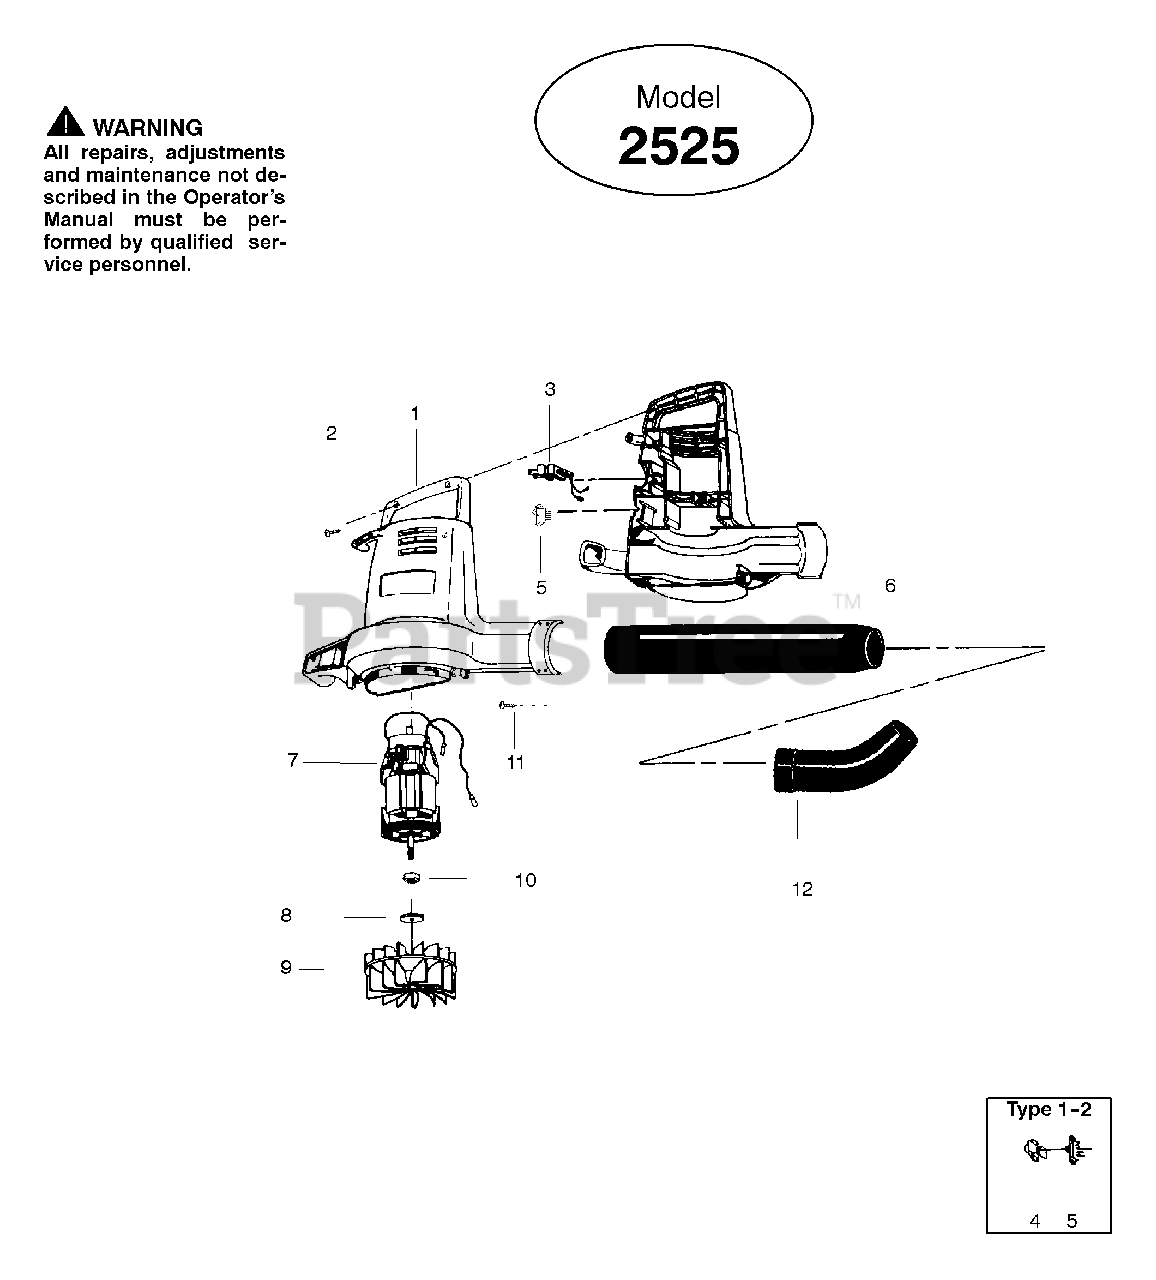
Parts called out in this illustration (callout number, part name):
1	Housing Set Type 1 & 2
1	Housing Set Type 3
3	Wire Harness Type 1 & 2
3	Wire Harness Type 3
4	Switch Cover Type 1 & 2 ONLY
5	Switch Type 1 & 2
5	Switch Type 3
6	Blower Tube
7	Motor Ass'y. Type 1
7	Motor Ass'y. Type 2 & 3
9	Impeller
10	Spacer (type 2 & 3 only)
12	Nozzle
